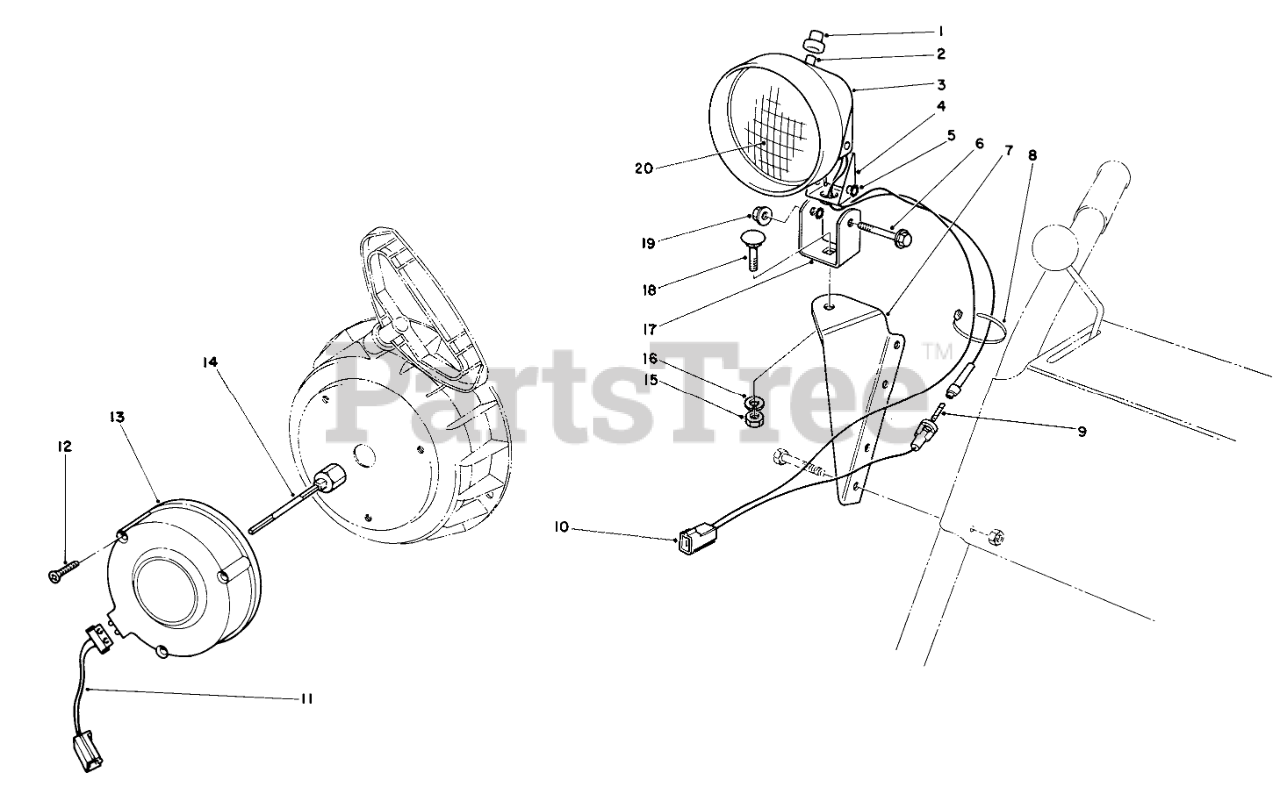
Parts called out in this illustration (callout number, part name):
1	BOOT-SWITCH
2	SWITCH ASM
3	Bucket-Headlamp
4	TO BE DISCONTINED-NOT NEEDED ON PRODUCT
5	WASHER-LOCK
6	SCREW-HH
7	LAMP MOUNT B
8	TIE-CABLE
9	Fuse-71/2 Amp.
10	WIRE ASM
11	Connector-Wire
12	SELF TAP SCREW
13	Alternator
14	Shaft-Alternator, 4 Inch
15	NUT-HEX
16	WASHER-LOCK
17	BRACKET
18	BOLT-CARR
19	NUT-HF
20	BEAM-SEALED
